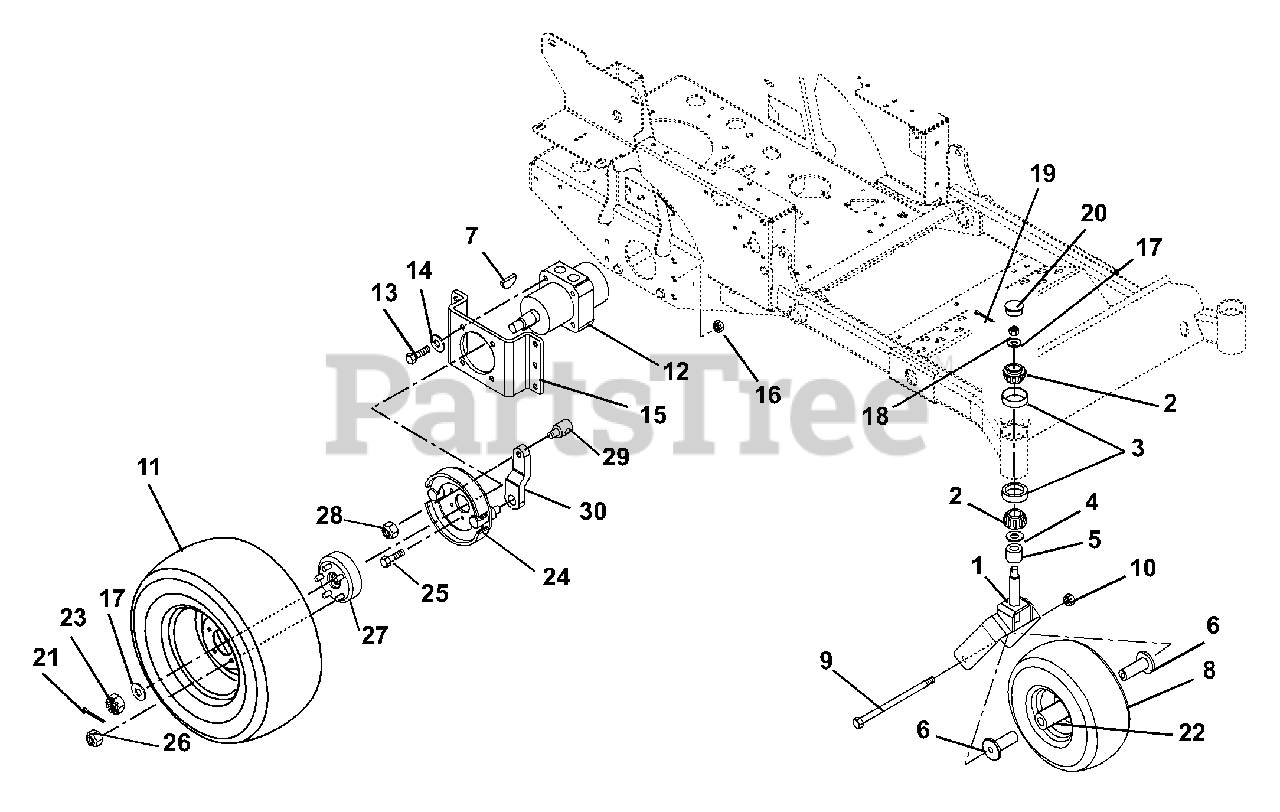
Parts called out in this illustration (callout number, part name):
1	WMT, FRONT FORK
2	BRG-CONE 1.0X.58
3	BRG-CUP1.980X.420
4	BEARING SEAL 1.5 X 2 X .18
5	SPACER 1.005X1.5075X.375
6	SPACER, WHEEL
7	KEY-WDRF .19X.75 HRD #9
8	ASSM TIRE\WHEEL 5.25 X 13.00
9	@BLT-HEX .50-13X7.50 GR5 YWZC
10	@NUT-LK-NYL-FLG .50-13 YWZC
11	TIRE/WHL 20X10-10 4PR
11	TIRE, 20X10 MULTI-TRAC C-S
12	MOTOR, HYD WHEEL
13	@BLT-HEX .38-16X1.00 GR5 YWZC
14	@WSHR-LK .38X.094 REG YWZC
15	BRKT, WHEEL MOTOR
16	@NUT-LK-NYL-FLG .38-16 YWZC
17	WSHR-FL-STL.755X1.375X.062YWZC
18	NUT, SLOTTED .75-16
19	@PIN-CTR .16X1.00 EXTPRSQCT YZ
20	CAP,DUST
21	@PIN-CTR EXTPRSQCT .09X1.25 YZ
22	BRG, 25MM ID X 52MM OD X 15MM
23	NUT-HEX-SL .75-20
24	BRAKE, MECHANISM W/ PADS
25	SCR-SKH M6X16 SHCS GR5 EP30
26	NUT-LUG .50-20 YWZC
27	HUB, 5-BOLT BRAKE DRUM
28	@NUT-LK-CTR-JAM .31-18 YWZC
29	PIN, PIVOT/TRUNNION
30	ARM, BRAKE HYDRO-GEAR
